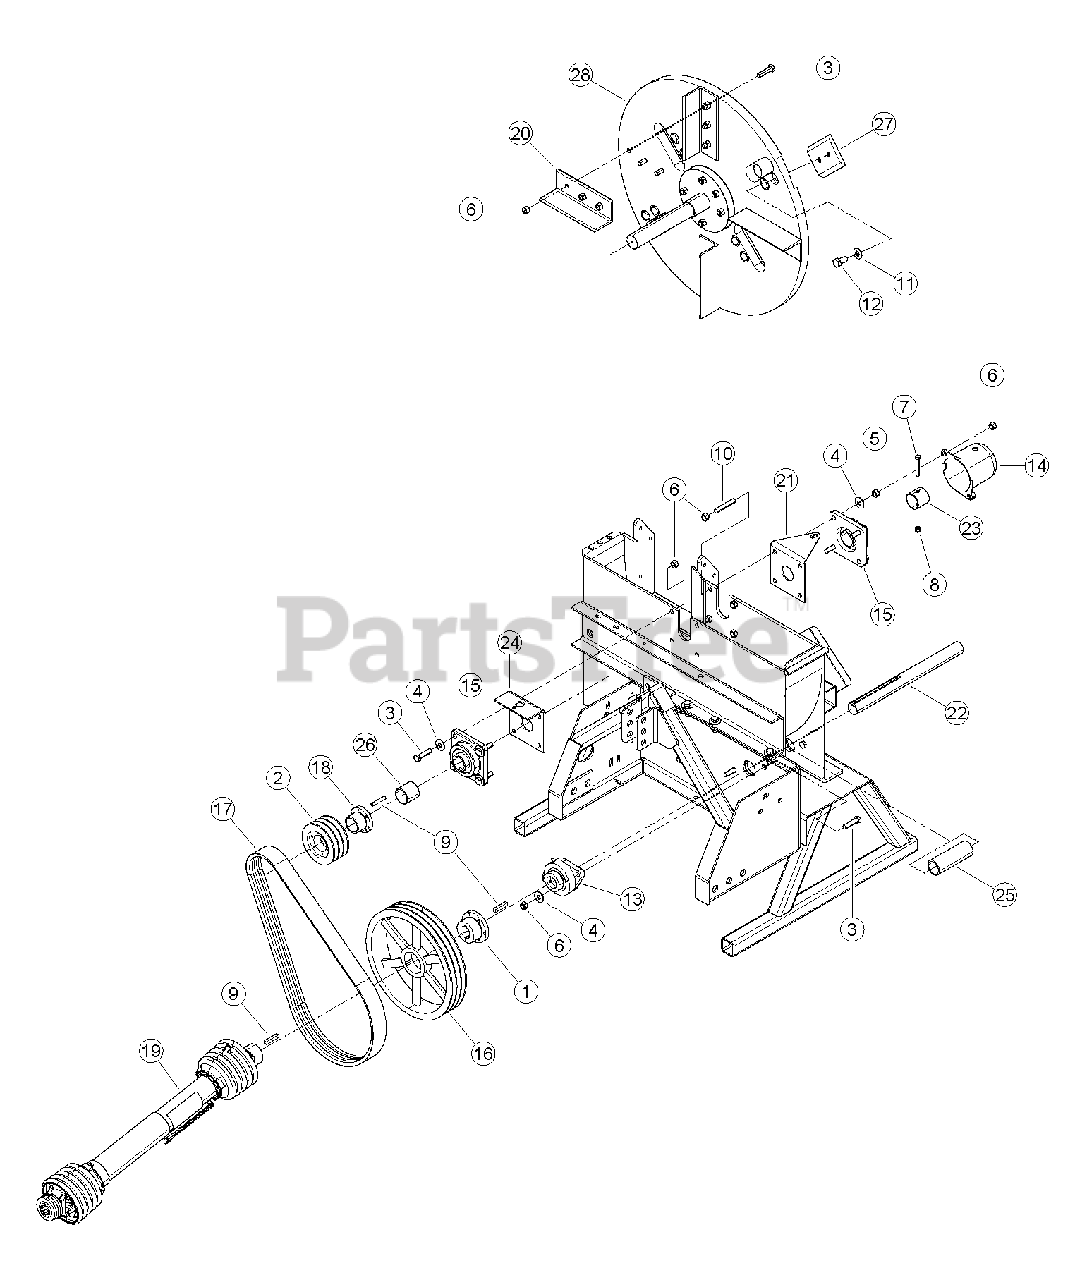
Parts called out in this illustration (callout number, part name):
1	BUSHING, SK 1-1/2
2	SHEAVE 3B4.8 SD
3	BOLT, 1/2 X 2 HEX HD GR5 ZP
4	WASHER, 1/2 FLAT ZP
5	NUT, 1/2 HEX NC ZP
6	NUT, 1/2 CENTERLOCK GRB ZP
7	BOLT, 3/8 X 2-1/2 HEX HD GR5 ZP
8	NUT, 3/8 NE NYLOCK ZP
9	KEY, 3/8 SQUARE X 2 LONG PLAIN
10	STUD, 1/2-13 X 3 LONG B7 ZP
11	WASHER, 5/8 SAE HARDENED
12	BOLT, M16 X 2.0 X 30 HEX HD W/PATCH
13	BEARING, 2 BOLT FLANGE 1-1/2 BORE
14	CAP, LARGE SHAFT
15	BEARING, 4 BOLT FLANGE 1-3/4 BORE
16	SHEAVE, 3B13.6 SK
17	BELT, BANDED CHIPPER
17	BELT, 3RB64
18	BUSHING, SD 1-3/4
19	DRIVESHAFT
19	DRIVELINE
20	PADDLE, BIG CHIPPER
21	BEARING BRACKET
22	JACKSHAFT, CHIPPER DRIVE
23	COLLAR, CHIPPER LOCK
24	WELDMENT, LEFT BEARING BRACKET
25	SHIELD, SHAFT
26	SPACER, 2.0 X 1.88
27	BLADE, BIG CHIPPER
28	ASSEMBLY, 9 INCH CHIPPER ROTOR
